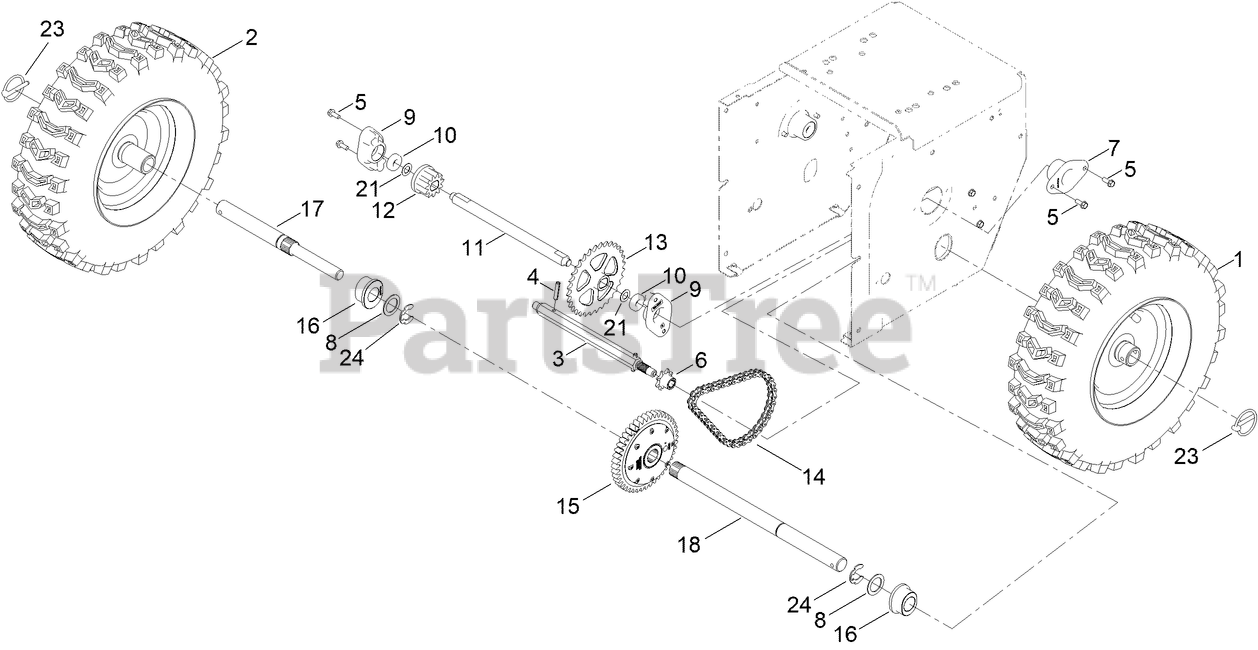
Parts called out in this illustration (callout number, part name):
1	LH WHEEL AND TIRE ASM
2	RH WHEEL AND TIRE ASM
3	SHAFT-HEX
4	PIN-ROLL, SLOTTED
5	SCREW-HWH
6	GEAR-PINION, 8 TOOTH
7	RETAINER-BEARING
8	WASHER-THRUST
9	RETAINER-BEARING, INTERMEDIATE
10	BEARING-WHEEL
11	SHAFT-INTERMEDIATE
12	TOOTH-GEAR, 11
13	SPROCKET-32T
14	CHAIN-ROLLER
15	TRANSMISSION-GT, DI300
16	BUSHING-AXLE
17	AXLE-RT, HD
18	AXLE -LT, HD
21	WASHER-PLAIN
23	PIN-KLIK
24	RING-RETAINING
